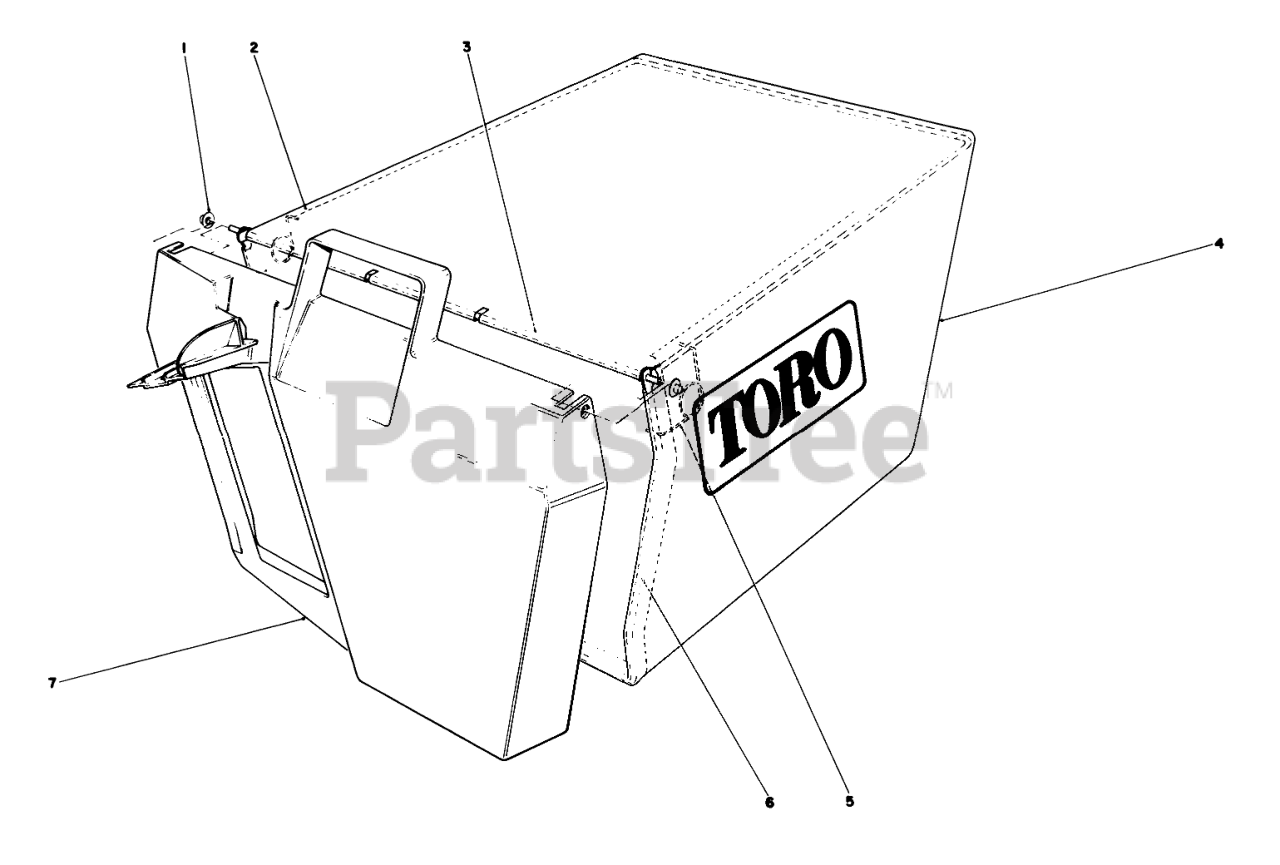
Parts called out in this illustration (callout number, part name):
1	NUT-PUSH
2	FRAME-BAG, UPPER
3	HINGE-DOOR, BAG
4	Bag
5	SPRING
6	BAG FRAME
7	Door Grass Bag
